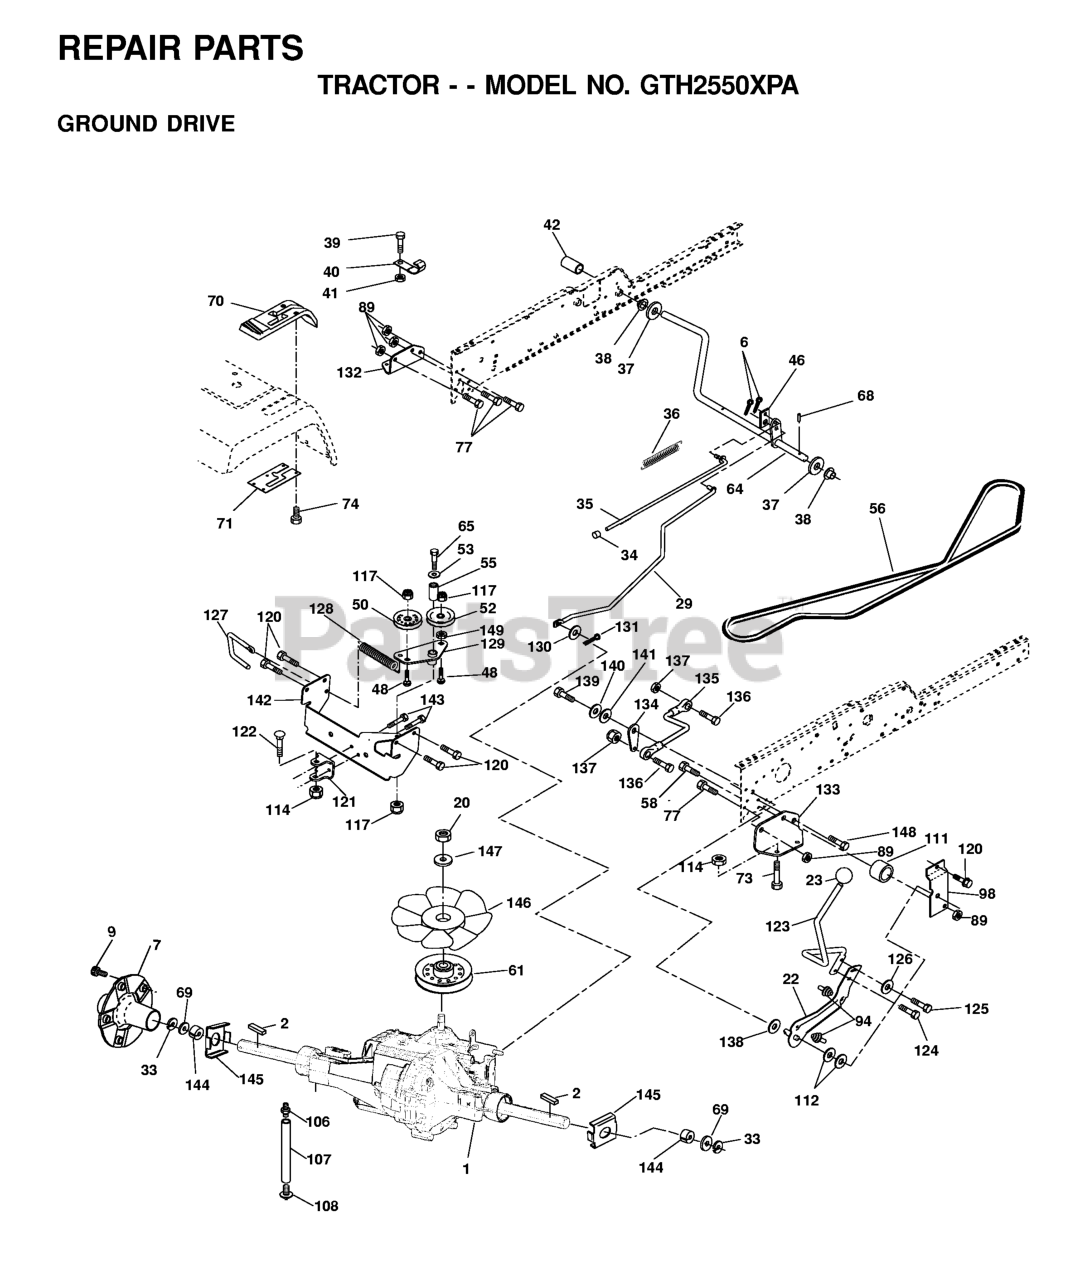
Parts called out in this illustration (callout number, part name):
6	COTTER PIN
7	HUB ASMBLY
20	NUT.HEX.1/2-20
23	KNOB.DELUXE.(PISTOL.GRIP).BLAC
29	BRAKE, ROD
33	E RING HYT
34	PLUNGER CAP
35	PARKING BRAKE ROD
36	SPRING DRIVE GROUND
39	Screw, Fin. #10-24 x 1
40	ACT-SWITCH T
41	Nut Centerlock 10-24 unc
42	PEDAL COVER
46	RETAINER SPRING
50	PULLEY.IDLER.FLAT
52	IDLER PULLEY
55	BEARING LT (2 2)
56	BELT, V GROUND DRIVE
58	BOLT.HEX.7/16-14.FINISHED
61	PULLEY, TRANSAXLE
64	SHAFT.ASM.PEDAL.BRAKE
68	ROLL PIN STD
71	PLATE CONSOLE SHIFT
72	LOCKNUT
73	BOLT HEX FLGHD 5/16-18X3 GR. 5
74	SCREW.HI-LO.CONSOLE
77	BOLT
89	Nut, Crownlock Hex 7/16-14 unc
94	FASTENER.XMAS.TREE
98	SHIFT BRACKET
106	O-RING KIT 70110
107	LINE.VENT.HYDRO-GEAR
108	CAP, VENT ASSY
111	SPACER SHIFT LEVER VGTH
112	WASHER NYLON HIGH TEMP
114	NUT.71038.31-18.HEX.NYLOCK
117	NUT LOCK FLG 3/8-16 UNC
120	SCREW 3/8-16X3/4
121	BRACKET STRAP TORQUE
122	Bolt RDHDSQ 5/16-18 Unc x 2-1/2
123	ROD, SHIFT
124	BOLT.SHOULDER.5/16-18X
126	WASHER.SRRTD.5/16
127	LINK CONTROL CLUTCH
128	SPRING DRIVE GRND
131	COTTER PIN
132	BRACKET MTG HYDRO 3500 LH VGT
133	BRACKET MTG HYDRO 3500 RH VGT
135	LINK ASM CONTROL HYDRO 3500
136	BOLT.FIN.HEX.5/16-18UNC X 1.00
137	LOCKNUT
138	THRUST WASHER
139	BOLT 1/4-28X3/4
140	LOCKWASHER
142	STRAP TORQUE HT-3500
143	Screw 5/16-18 x 1/2 Hex, Self Tapping 5/16-18 x 1/2
144	WASHER, SPACER AXLE
145	WASHER.AXLE.FLANGE.HG-3000
146	FAN 7" HYDRO
148	SCREW THDROL 3/8-16 X 1-1/2
149	WASHER
